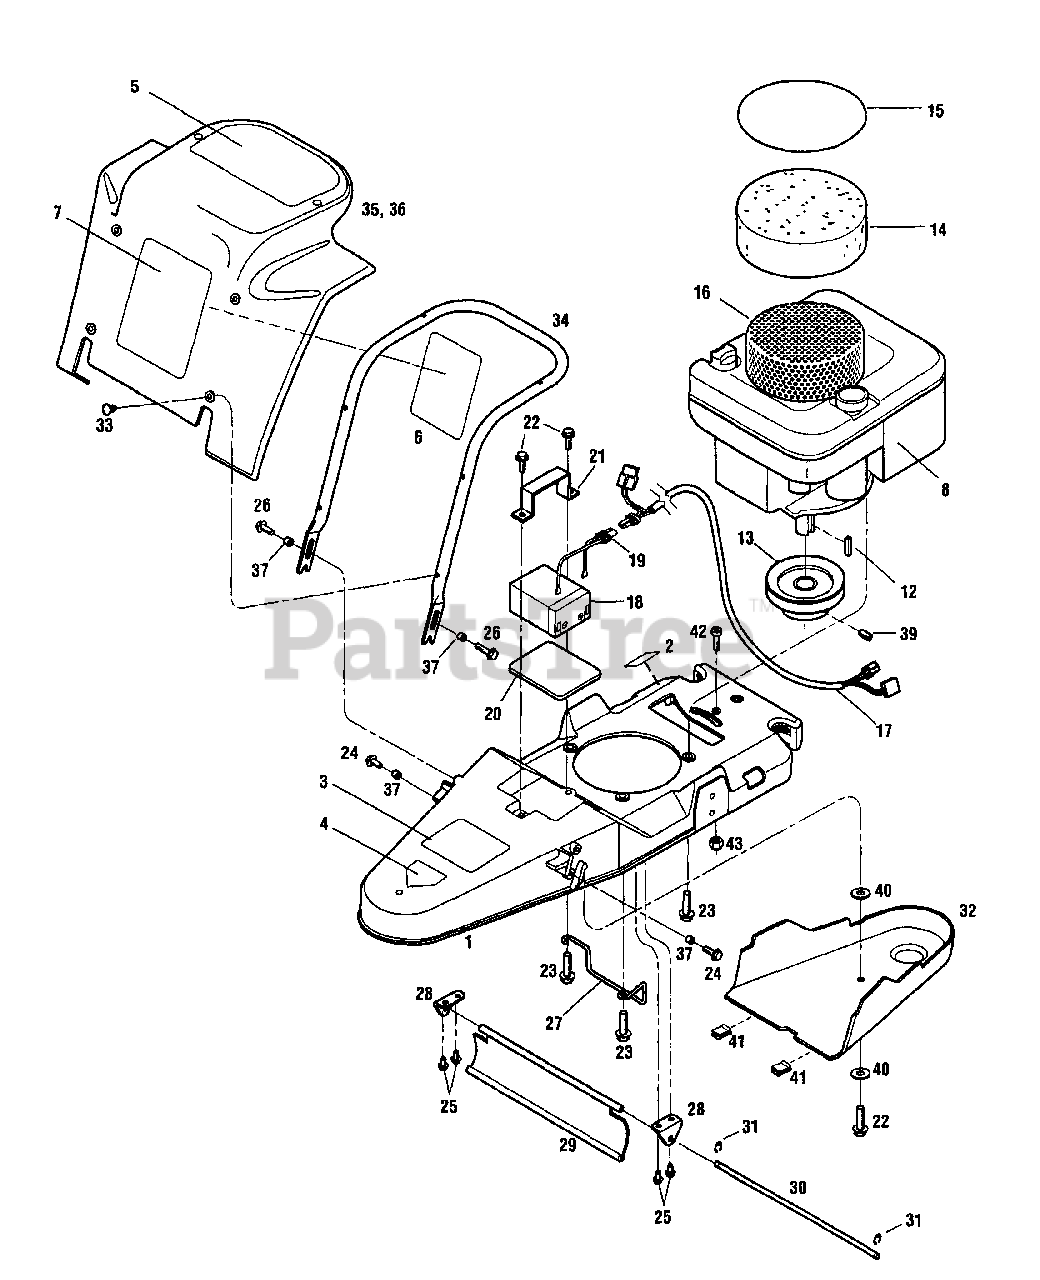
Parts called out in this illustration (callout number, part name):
1	Deck with decals
2	Decal-Hot Surface
3	Decal-Warning/Thrown Objects
4	Decal-Danger Feet/Hands
5	Decal-Engine Cover
6	Decal-Parallel Trim Control
7	Decal-Logo, 5HP.
12	Key, 3/16" x 1" Sq
13	Pulley, 4" OD
14	Engine Debris Guard/Foam
15	O-Ring/Engine Debris Guard
16	Engine Debris Guard
17	Wire Harness.
18	Battery.
19	Battery Connector.
20	Battery Pad.
21	Battery Bracket.
22	Hex Hd. Flange Screw, 5/16-18 x 1
23	Hex Hd. Flange Screw, 3/8-16 x 1-1/2
24	Hex Hd. Flange Screw, 1/4-20 x 3/4
25	Hex Hd. Flange Screw, 1/4-20 x 5/8
26	Hex Hd. Flange Screw, 1/4-20 x 1
27	Belt Guide
28	Flap Bracket
29	Deflector Shield
30	Deflector Shield Rod
31	E-Ring, 5/16"
32	Belt Cover
33	Push-In Fastener
34	Engine Cover Support
35	Engine Cover w/decals.
36	Engine Cover w/decals.
39	Set Screw
40	Washer
41	Clip
42	Socket Hd. Capscrew, 1/4-20 x 1
43	Toplock Nut, 1/4-20
